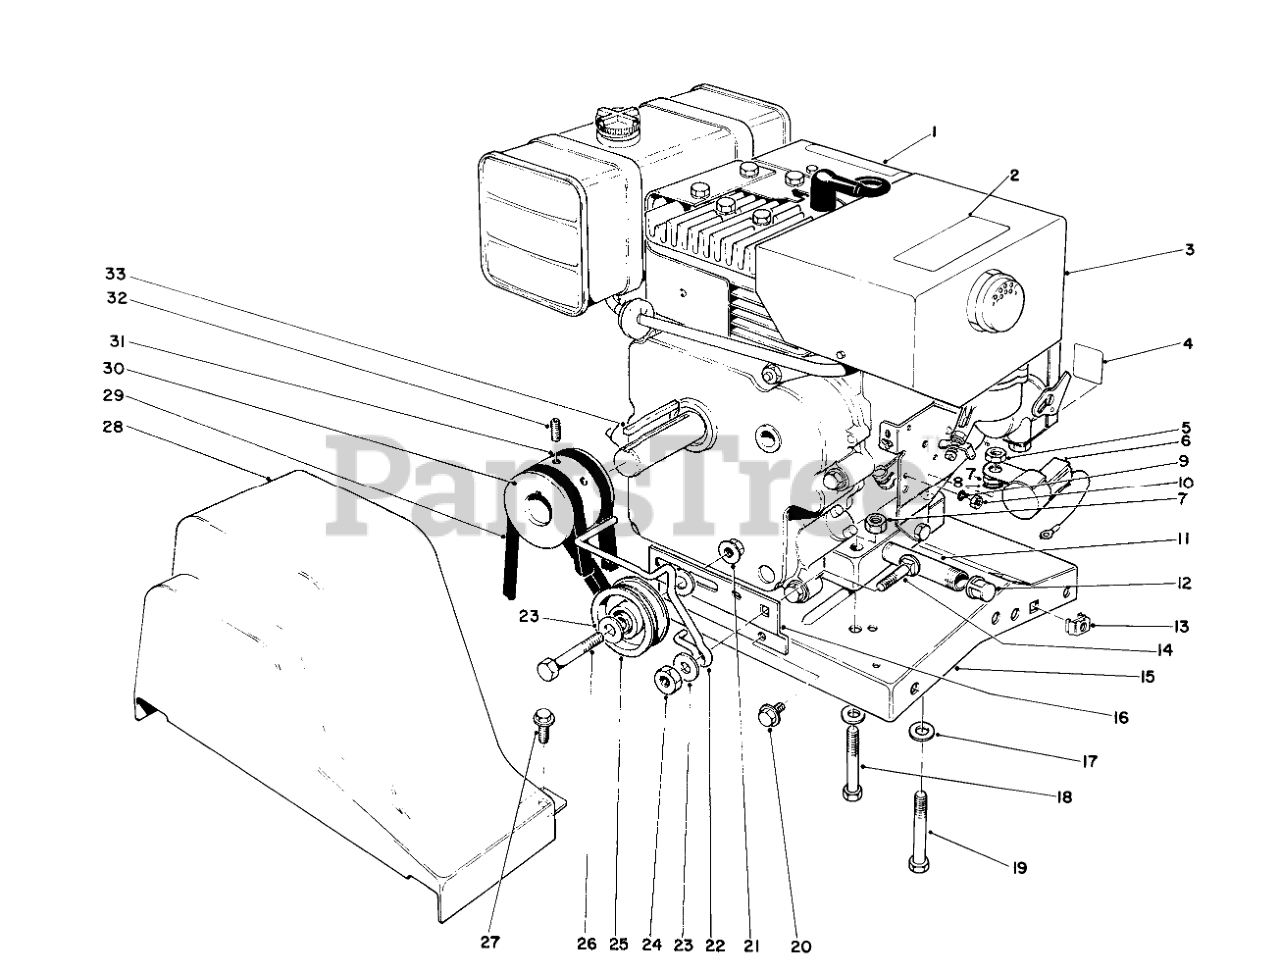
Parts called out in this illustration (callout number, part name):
1	CAUTION DECAL
2	HOT SURFACE DECAL
3	Engine
4	CHOKE DECAL
5	NUT-HEX, SIDE DEFORM
6	INTERLOCK MODULE
7	NUT-LOCK, NI
8	WASHER-LOCK, INTERNAL
9	WASHER-LOCK/INT
10	NUT-LOCK
11	NIPPLE-PIPE
12	CAP-PIPE
13	RETAINER NUT
14	SCREW-CARR
15	Base-Engine
16	BELT IDLER BRKT
17	WASHER-PLAIN
18	SCREW-HH
19	SCREW-HH
20	SCREW-HHFTF
21	NUT-HHF, WHIZ
22	BELT GUIDE
23	WASHER-FLAT
24	NUT-LOCK, NI
25	PULLEY B
26	SCREW-HH
27	SCREW-HWH
28	BELT GUARD
29	V-BELT
30	ENGINE PULLEY
31	V-BELT
32	Screw-Set
